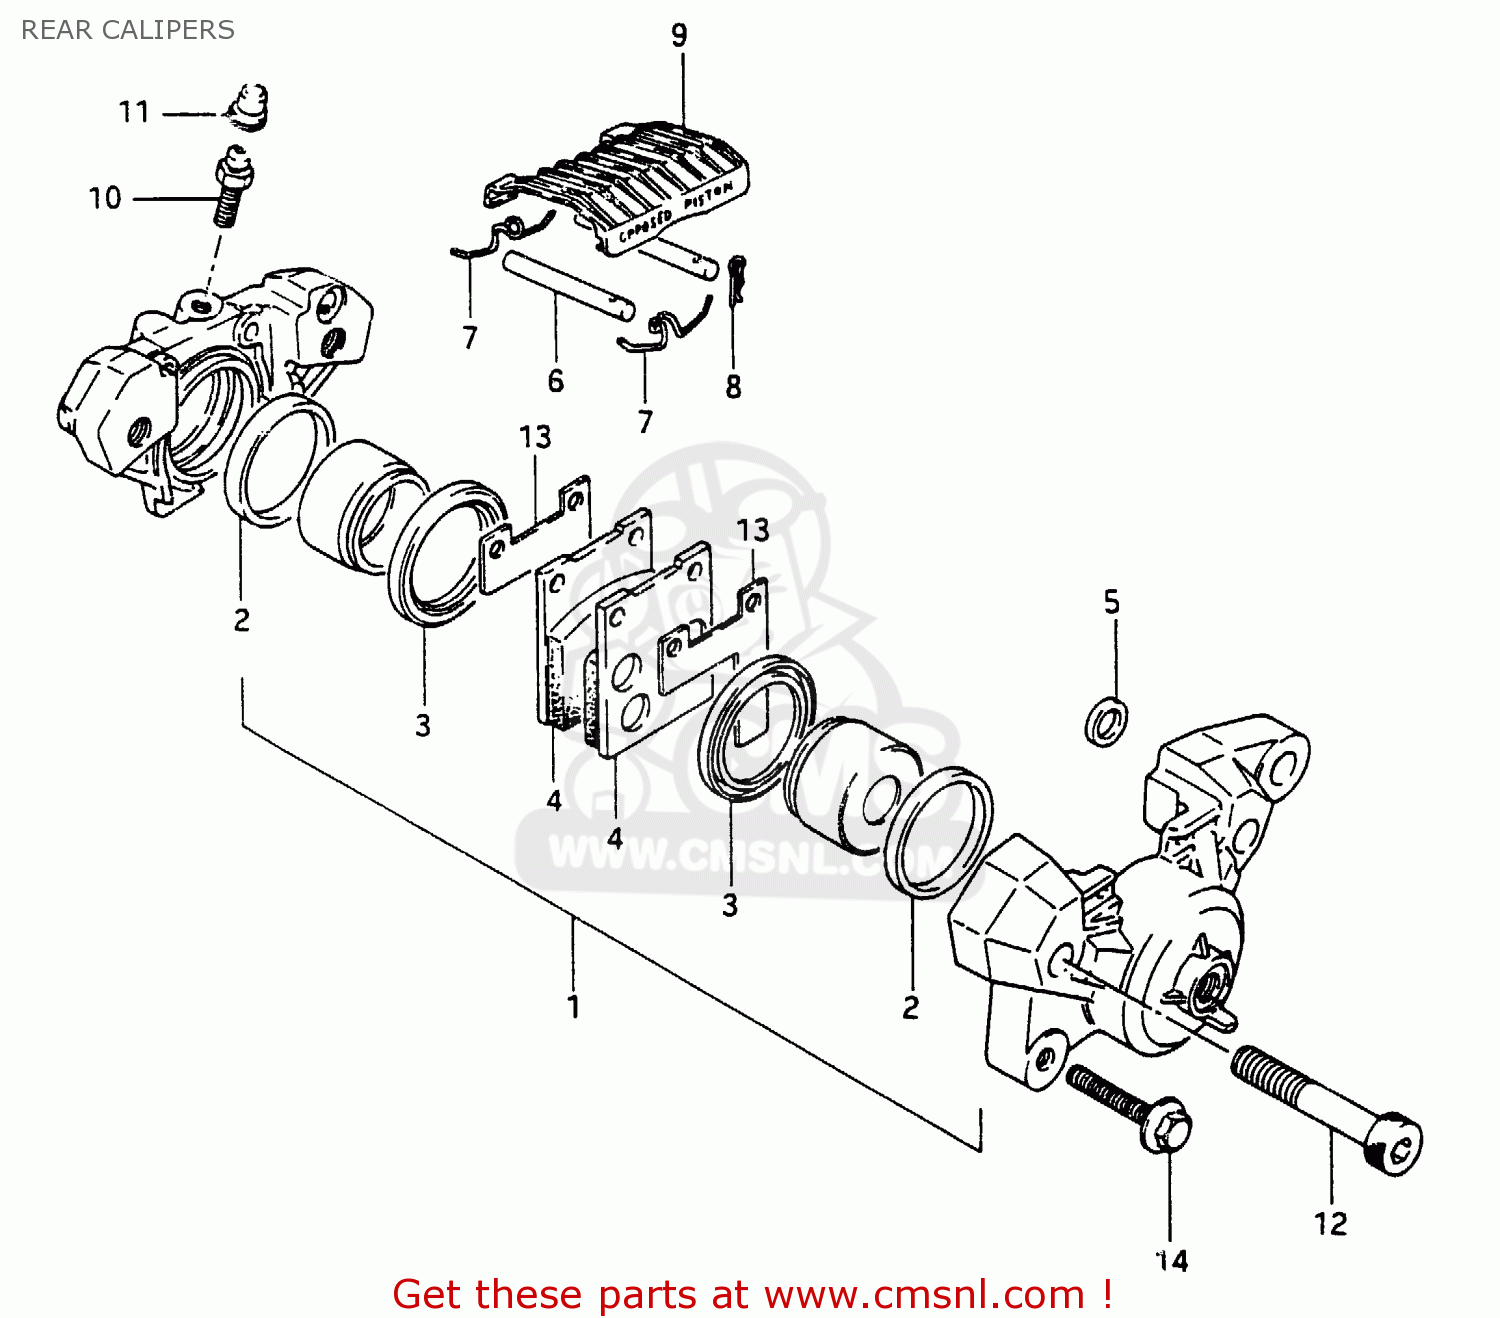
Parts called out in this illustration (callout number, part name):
1	PISTON SET
2	SEAL,PISTON
3	BOOT
4	PAD
5	SEAL,JOINT
6	PIN,PAD
7	SPRING
8	CLIP,PAD PIN
9	COVER
10	BLEEDER
11	CAP,BREATHER
12	BOLT
13	SHIM
14	BOLT
